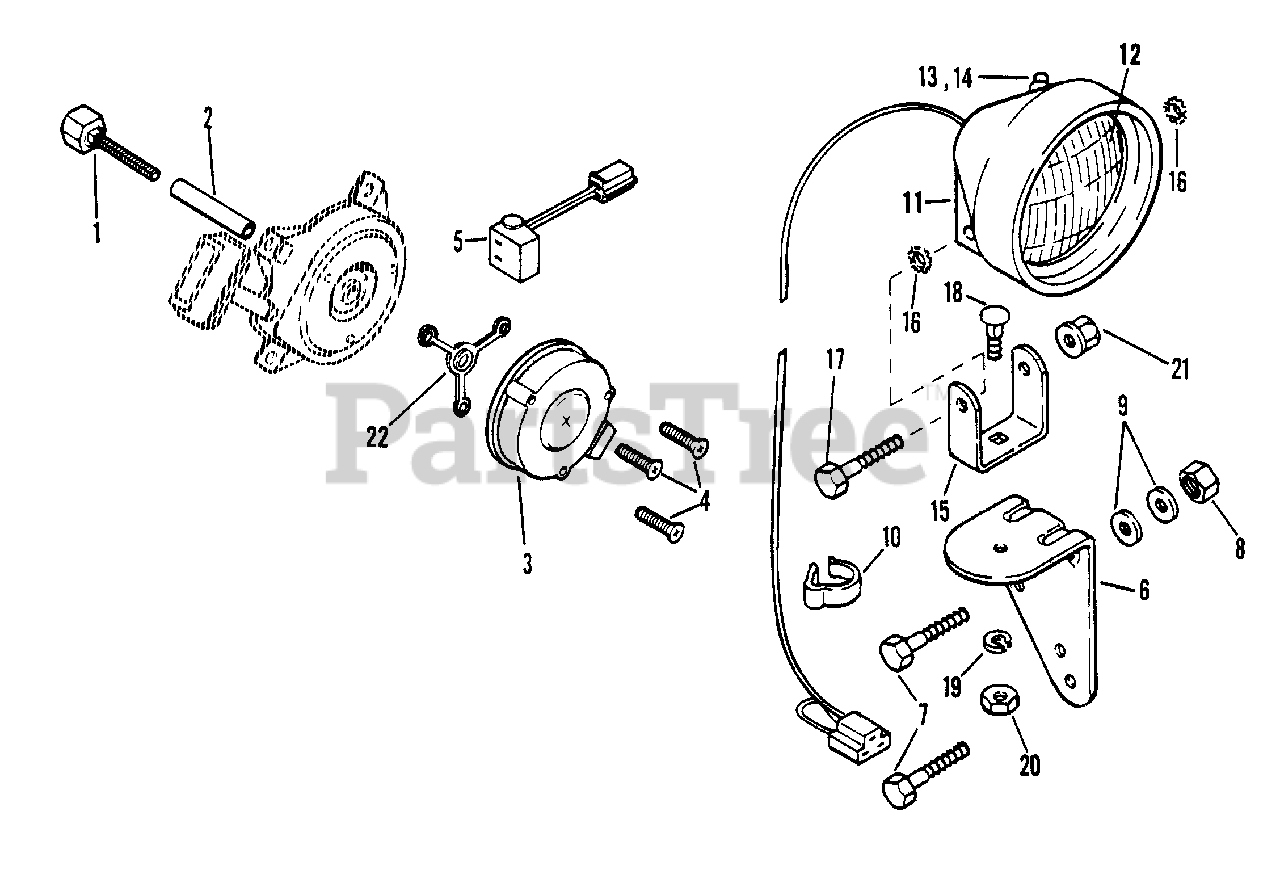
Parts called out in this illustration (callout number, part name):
1	Alternator Shaft 4" 8 HP
2	Centering Tube 2.7 to 7 HP
2	Centering Tube 8 and 10 HP
3	Alternator
4	SCR-TAP 8-18X1.12 CRFH PL B
4	SCR-TAP 8-18X1.25 CRFH PL B
5	Lighting Connector
6	HEADLIGHT BRACKET
7	BLT-HEX .25-20X1.75 PL GR2
8	NUT-LK-CTR .250-20 PL
9	WSHR-FL-STL .380X.875X.179 PL
10	CONDUIT CLAMP 2 WIRE
11	HEAD LIGHT ALTERNATE 024562
11	HEADLIGHT
11	HEADLIGHT ALTERNATE 024570
12	HEAD LIGHT
13	PUSH BUTTON SWITCH
14	SWITCH BOOT
15	U-BRACKET
16	WSHR-LK-EXT .313X.030 PL
17	BLT-HEX .31-18X2.50 PL GR2
18	BLT-RDHDSQNK .31-18X1.00 PL
19	WSHR-LK .312X.097 PL HVY
20	NUT-HEX .312-18
21	NUT-FLG. .312-18 PL
22	SPACER-ALTERNATOR
